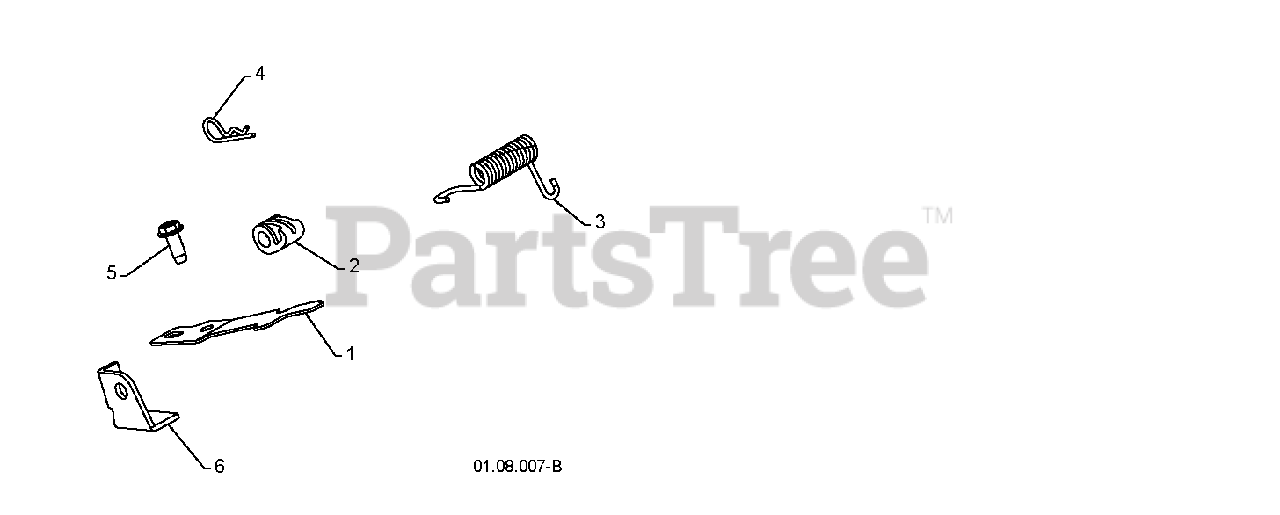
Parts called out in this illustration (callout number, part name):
1	SPRING.INTERLOCK
2	RP CAM.INTERLOCK.RELEASE
3	RP SPRING, TORSION
4	SPRING RETAINER
5	SCREW 14-20 X 5/8
6	STOP.INTERTLOCK
